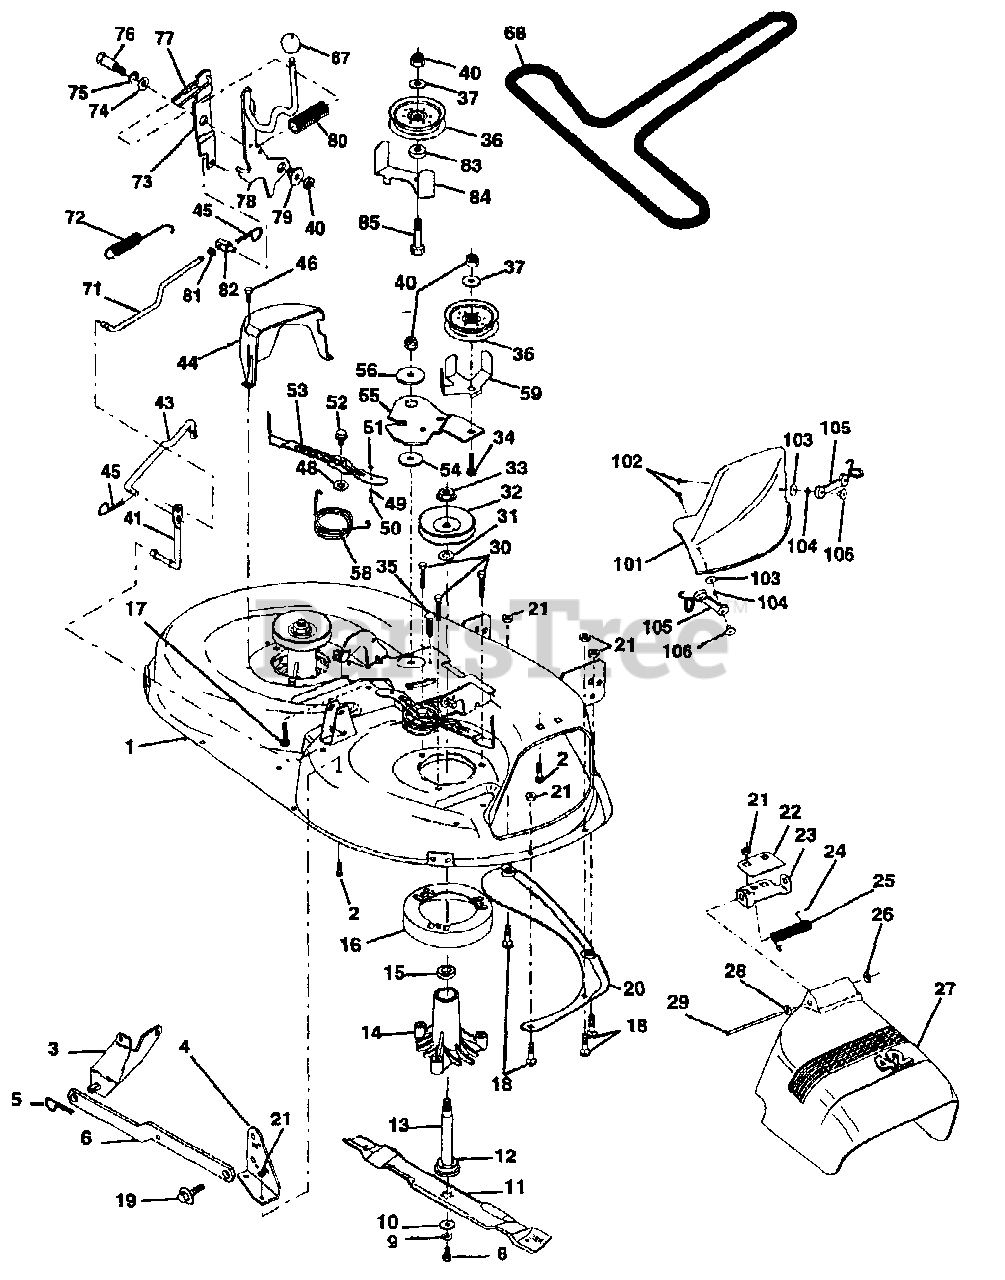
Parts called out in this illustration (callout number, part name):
1	Deck Asm Mower 42"
2	Bolt Rdhd Sqnk 5/16-18unc X3/4
3	Bracket Asm Fr Sway Bar
4	Bracket Asm Deck Sway Bar 42"
5	Retainer Spring
6	Arm Suspension Rear
8	Bolt 3/8-24x1 25 Gr8 Patched
9	Washer Lock Hvy 3/8 Unplated
10	Washer Hard Blade Mower Vented
11	Blade
12	Bearing Ball #6204 (Mandrel)
13	Shaft Asm W/lower Bearing
14	Housing Mandrel Vented (machd)
15	Bearing Ball Mandrel
16	Stripper Mower Vented
17	Bolt Rdhd Sqnk 3/8-16 X 1-1/4
18	Bolt Rdhd Sqnk 5/16-18 X 5/8
19	Bolt Shoulder 5/16 - 18
20	Baffle Vortex 42
21	Nut Crownlock 5/16-18
22	Stiffener Bracket 42" deck
23	Bracket Deflector Mower 42"
24	Cap Sleeve 80x 112 Blk Mower
25	Spring Torsion Deflector 2 52
26	Nut Push Phos & Oil
27	Shield Deflector Mower 42" Blk"
28	Washer 11/32 X 5/8 X 16 Ga
29	Rod Hinge 42" 6 75 Wlg
30	Screw Thdrol Hex Head
31	Washer Spacer Mower Vented
32	Pulley Mandrel 42"
33	Nut Flg Top Lock Cntr B 9/16
34	Bolt Rdhd 3/8-16uncx1-3/4 Gr5
35	Fastner Christmas Tree
36	Pulley Idler Flat 3 060
37	Washer 13/32 X 13/16 X 16 Ga
40	Nut Crownlock 3/8-16
41	Rod Pivot W/nibs
43	Rod Clutch Secondary W/nibs
44	Guard Mandrel LH Black
45	Spring Retainer 1" Zinc/cad
46	Screw Hex Thd Cut 1/4-20x5/8 T
48	Washer Hardened Smaller
49	Roller Asm Cam Follower 42" dec
50	Bolt Shldr 10-24 Zinc Gr 5 42"
51	Nut Lock #10-24 Unc
52	Bolt Shoulder 5/16-18
53	Arm Asm Pad Brake
54	Washer Hardened
55	Arm Idler 42" mower LT/YT
56	Spacer Retainer Pm Mower
58	Spring Torsion Brakes
59	Guard Tuv Idler
67	Knob Rd 1/2-13 Plstc Thds Blk
68	V-Belt Mower
71	Rod Clutch Primary 38/42
72	Spring Return
73	Arm Clutch Secondary
74	Washer 25/32 X 1-5/8 X 16 Ga
75	Ring Klip #t5304-75
76	Bolt Shoulder 3/8-16 Unc 1 44
77	Keeper Spring 4 000
78	Arm Asm Clutch Primary
79	Bushing 747 Od X 794 Lg Brass
80	Spring Clutch Mower 2 750 Zinc
81	Nut Hex Jam 3/8-16 unc
82	Trunnion Adj.
83	Washer Sintered
84	Keeper Belt Idler Fixed
85	Bolt Carriage 3/8-16 x 2-1/2 Gr.5
101	Cover Mulching 42" Black
102	Screw
103	Washer Lock #10
104	Washer #10
105	Latch Asm Bagger
106	Nut Weld .327/.304 #10-24
